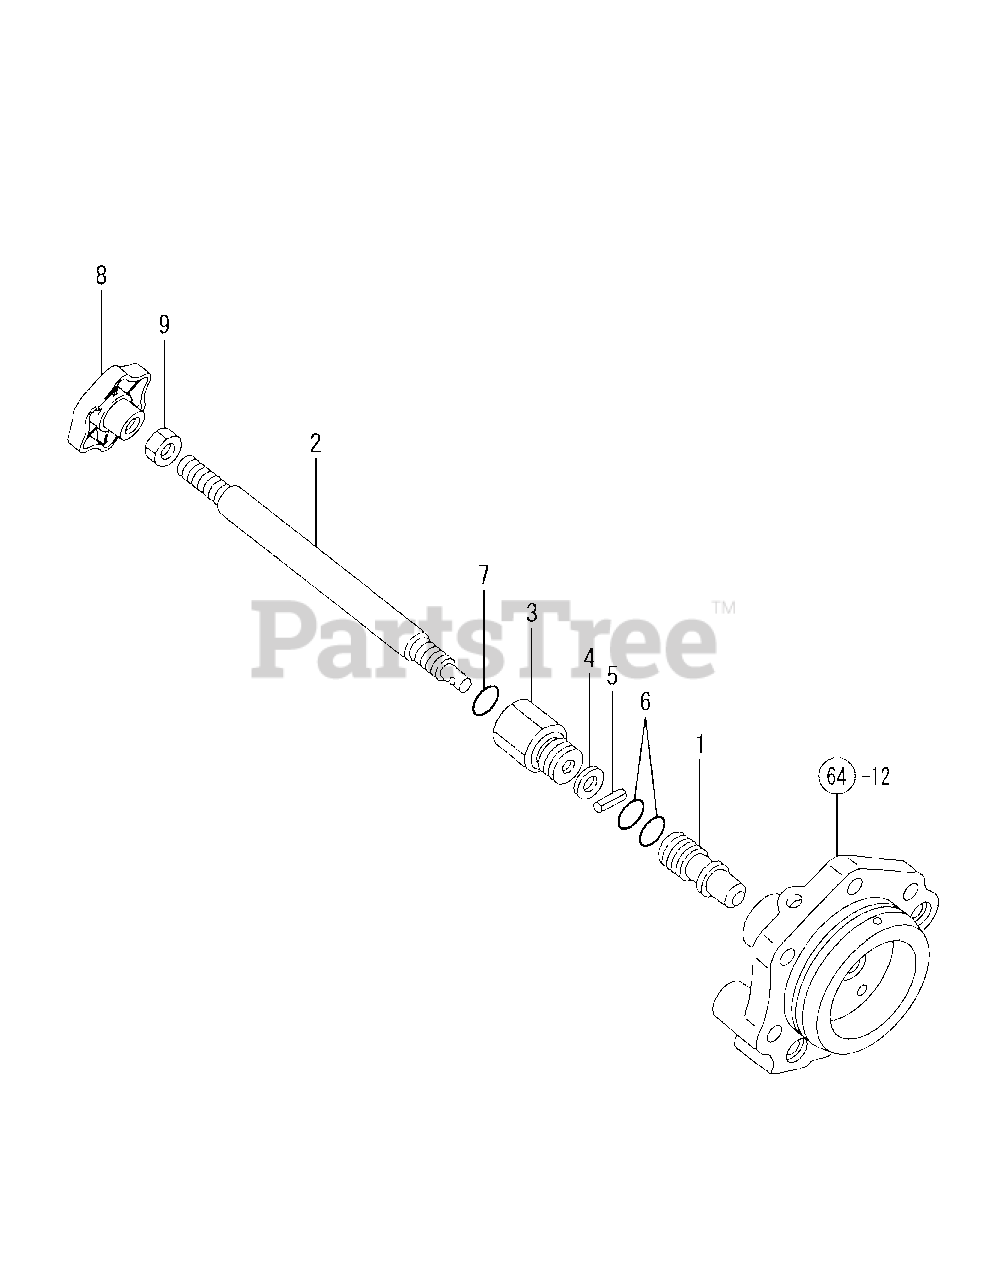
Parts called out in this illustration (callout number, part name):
5	SPRING PIN 4X12
6	O-RING 1A P-11.0
7	PACKING, P 12.0
8	KNOB,STOP VALVE
